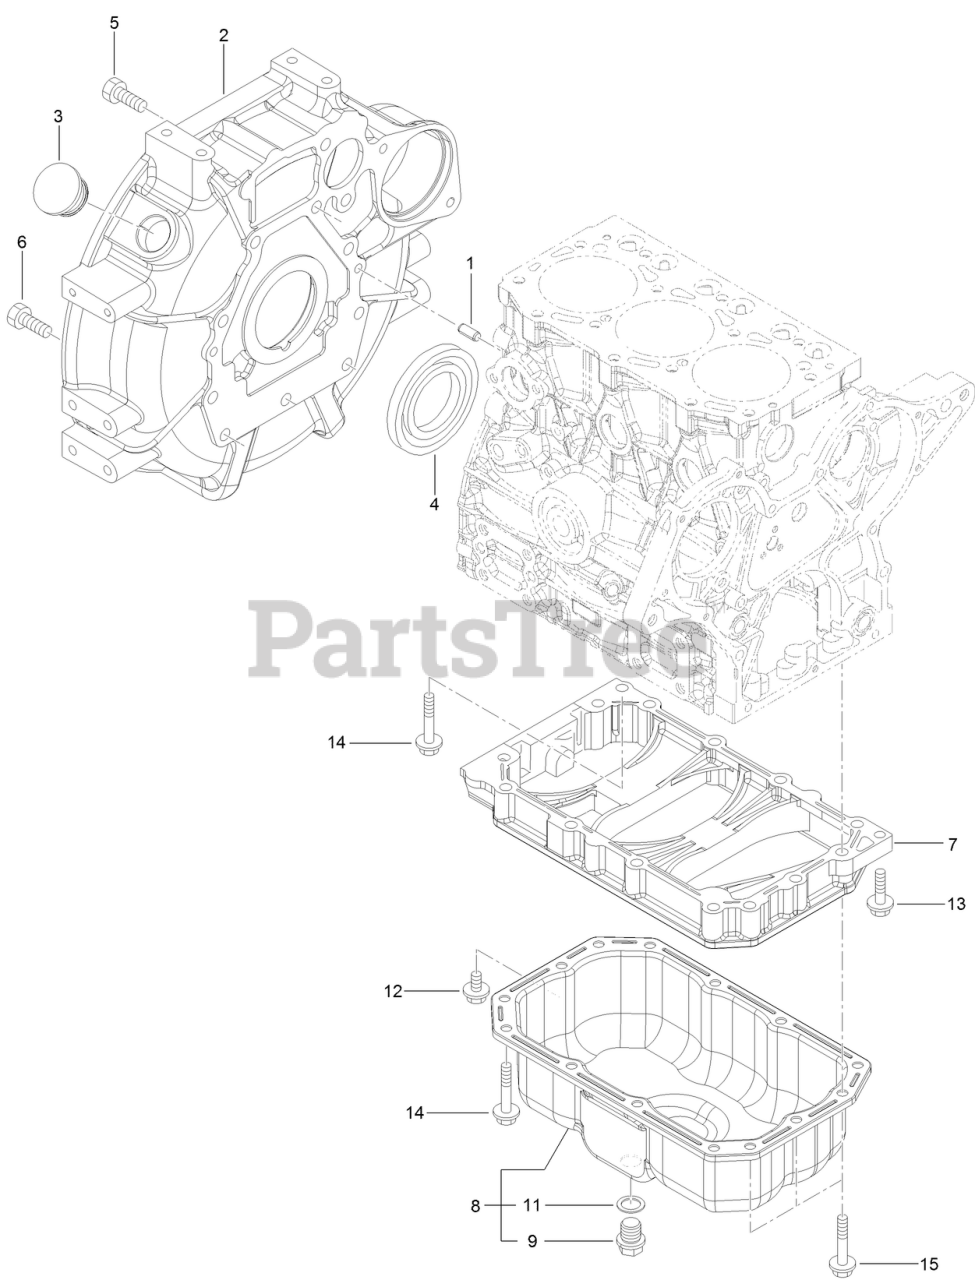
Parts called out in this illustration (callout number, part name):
2	HOUSING-FLYWHEEL
4	SEAL-OIL
7	SPACER-OIL PAN
8	OIL PAN ASM
11	WASHER-SEAL
